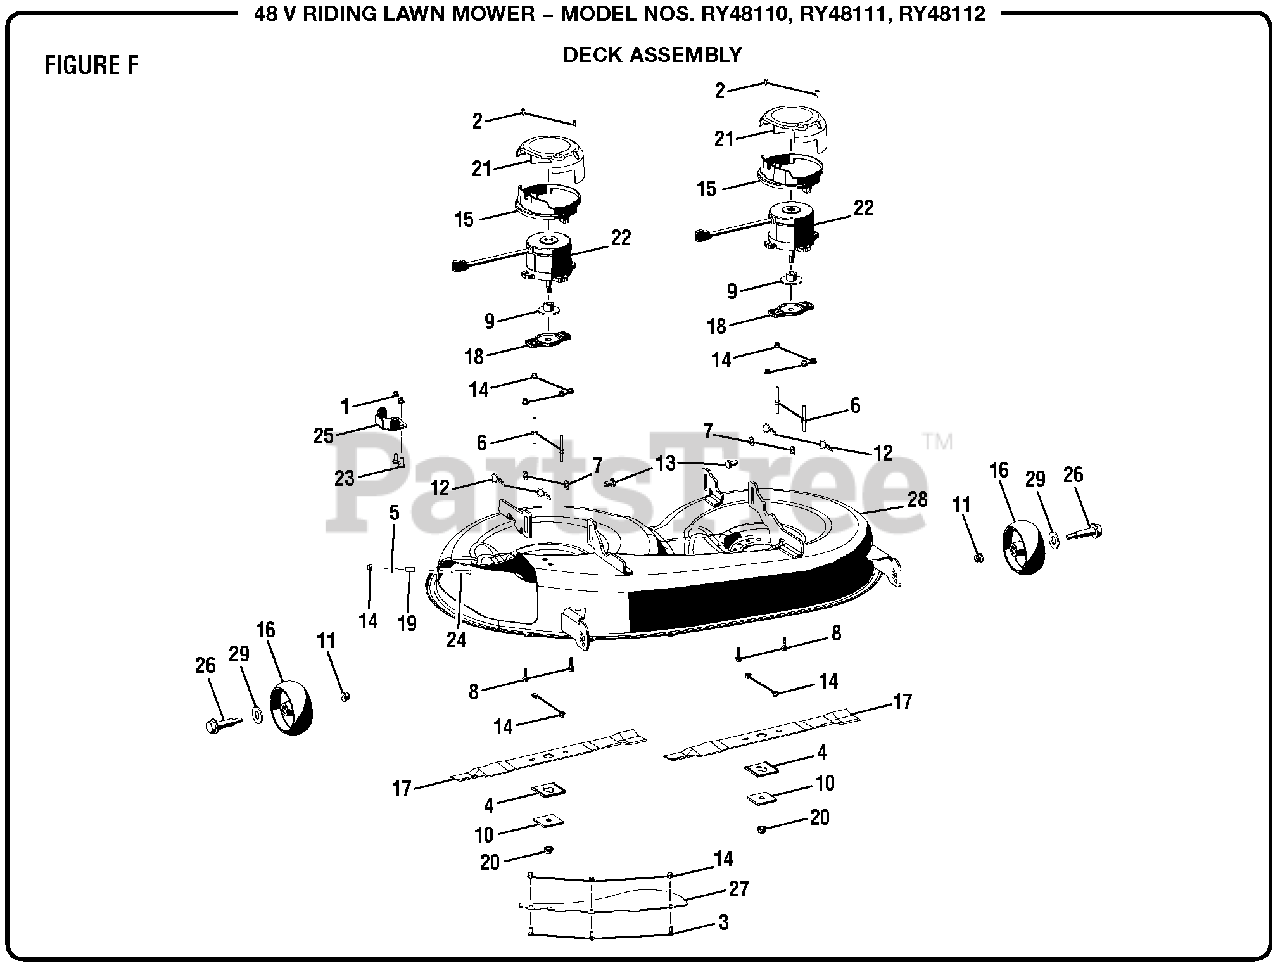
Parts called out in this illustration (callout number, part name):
1	Flange Nut (M8 x 1.25)
2	Screw (M4.2 x 13 mm)
3	Carriage Bolt (M6 x 16 mm)
4	Blade Spacer
5	Washer (OD18 x ID6.4 x 1.6t)
6	Threaded Stud (M6 x 35 mm)
7	Washer (OD20 x ID10.5 x 2t)
8	Flange Bolt (M6 x 25 mm, Hex Hd.)
9	Motor Axle Bushing
10	Metal Blade Retainer
11	Lock Nut (M10 x 1.5 mm)
12	Cotter Pin (10 mm)
13	Lifting Plate Pin
14	Flange Lock Nut (M6 x 1.00)
15	Motor Cover
16	Front Deck Roller Wheel (124.5 Dia.)
17	Mulching Blade
18	Blade Holder
19	Deck Bagger Chute Mounting Shaft
20	Flange Lock Nut (M10 x 1.25)
21	Motor Cover Cap
22	Deck Motor
23	Carriage Bolt (M8 x 20 mm)
24	Screw (M6 x 40, Soc Hd.)
25	Mounting Mulch Door Bracket
26	Shoulder Bolt (M10 x 70 mm)
27	Butterfly Bracket
28	Mower Deck w/Brackets
29	Spring Washer (OD20.5 x ID17 x 0.3t)
